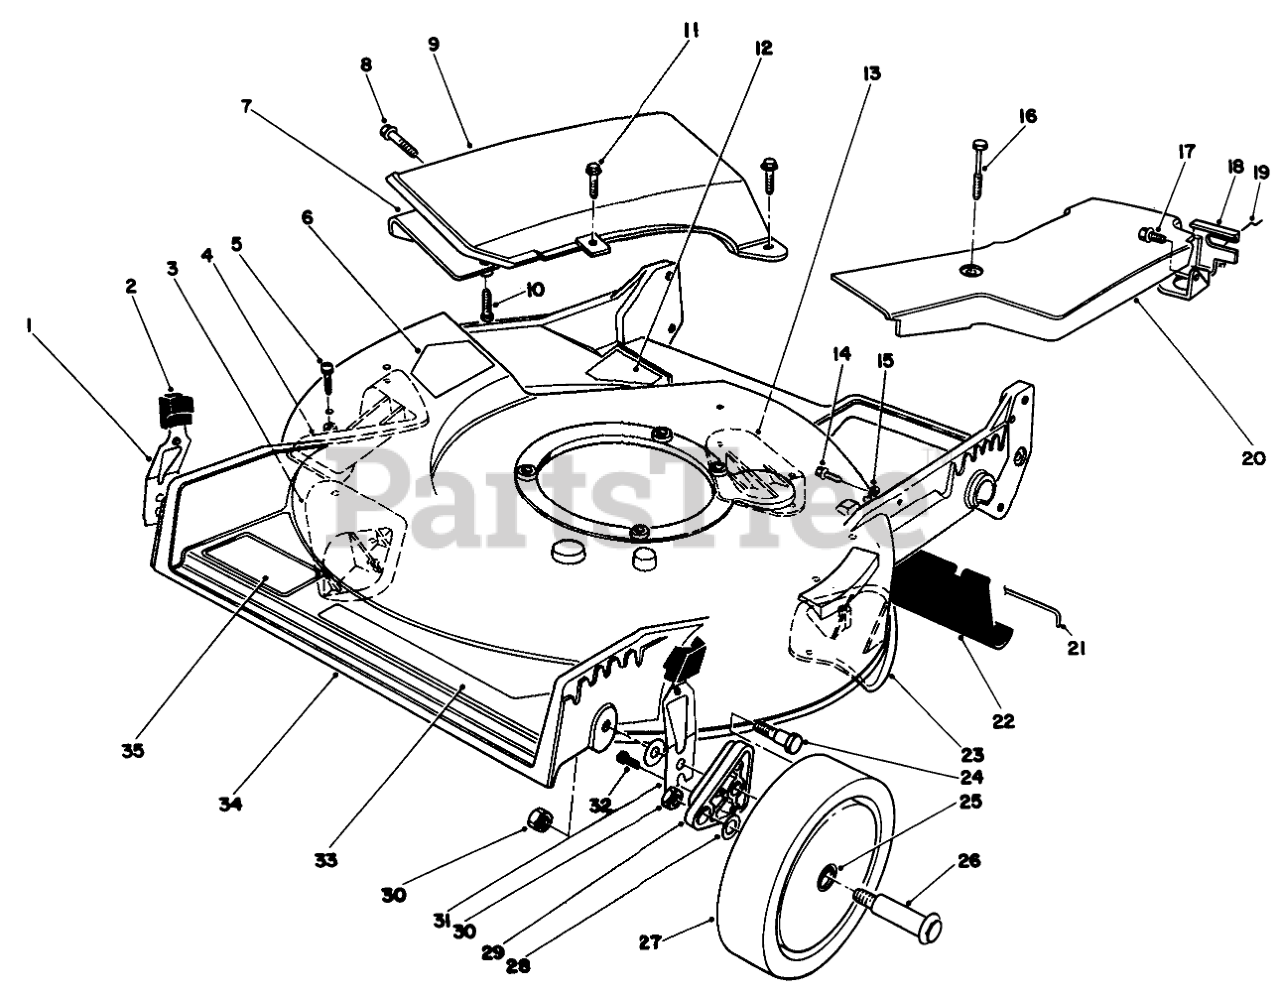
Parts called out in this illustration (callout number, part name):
1	RH SPRING ARM ASSEMBLY
2	KNOB-ARM
3	KICKER
4	KICKER
5	#8 X .625" PHILPS PAN H
6	DECAL-DANGER
7	Deflector-Recycler
8	SCREW AND WASHER ASM
9	Cover Assembly (Incl. Ref. #7 & 10)
10	Screw-Plastite
11	SCREW-HWH
12	DECAL - DANGER
13	KICKER
14	SCREW
15	CLAMP-CABLE
16	SCREW-HHFTF
17	SCREW-HWHTF
18	Bracket-Adj. Trac
19	RETAINER-CABLE
20	BELT COVER
21	ROD-SHIELD
22	SHIELD-TRAILING
23	KICKER
24	SCREW-SHOULDER
25	BUSHING
26	WHEEL BOLT
27	Wheel & Tire Assembly (Incl. Ref. #26)
28	WASHER
29	ARM-PIVOT, FRONT
30	Nut
31	LH SPRING ARM ASSEMBLY
32	SCREW-HWH
33	DECAL - DECK
34	Housing Assembly (Incl. Ref. #3-6, 12, 13, & 23)
35	DECAL
